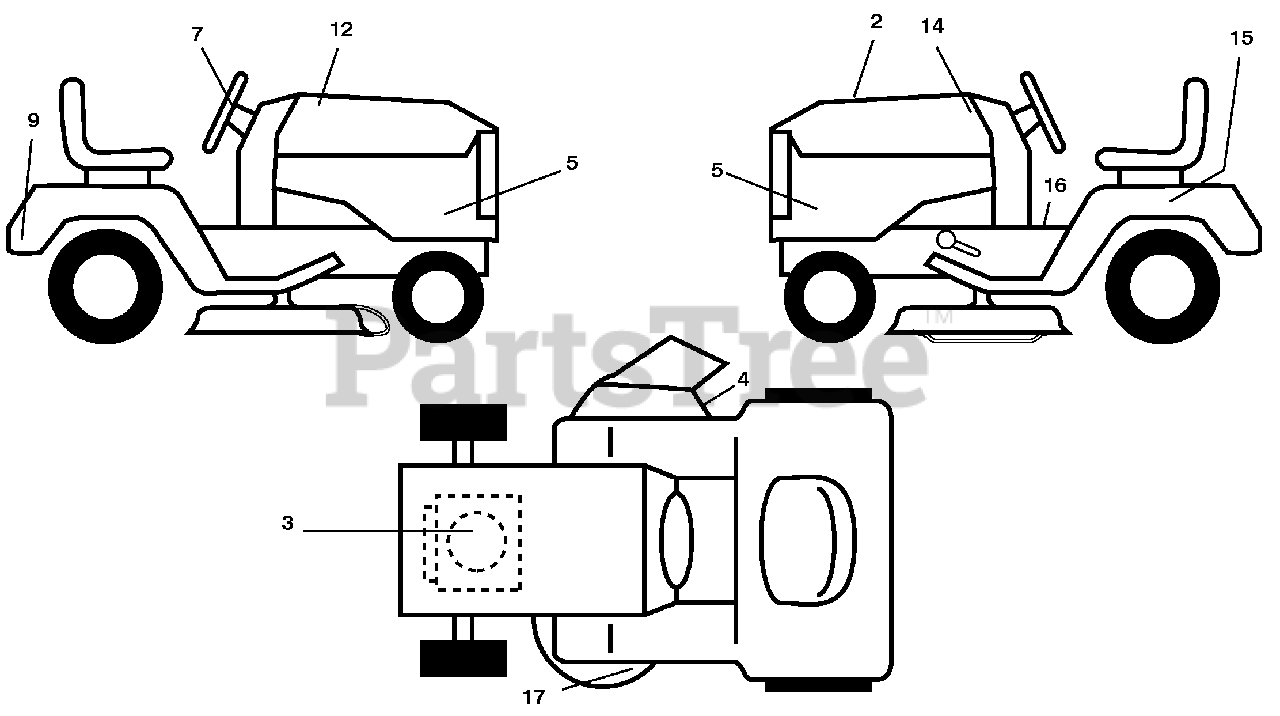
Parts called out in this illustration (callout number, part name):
2	Decal, Replacement
3	Decal, Engine HP
4	Decal, Warning
5	Decal, SDPNL
7	Decal, Ins Str Wh
9	Decal, Fender
12	Decal, Hood RH
14	Decal, Hood LH
15	Decal, Caution, Battery
16	Decal, Fender Warning Eng/Fr
17	Decal, V-Belt Sch.
17	Decal, Handle Lft Height Adj.
17	Manual, Operator's E&F
17	Manual, Parts E&F
